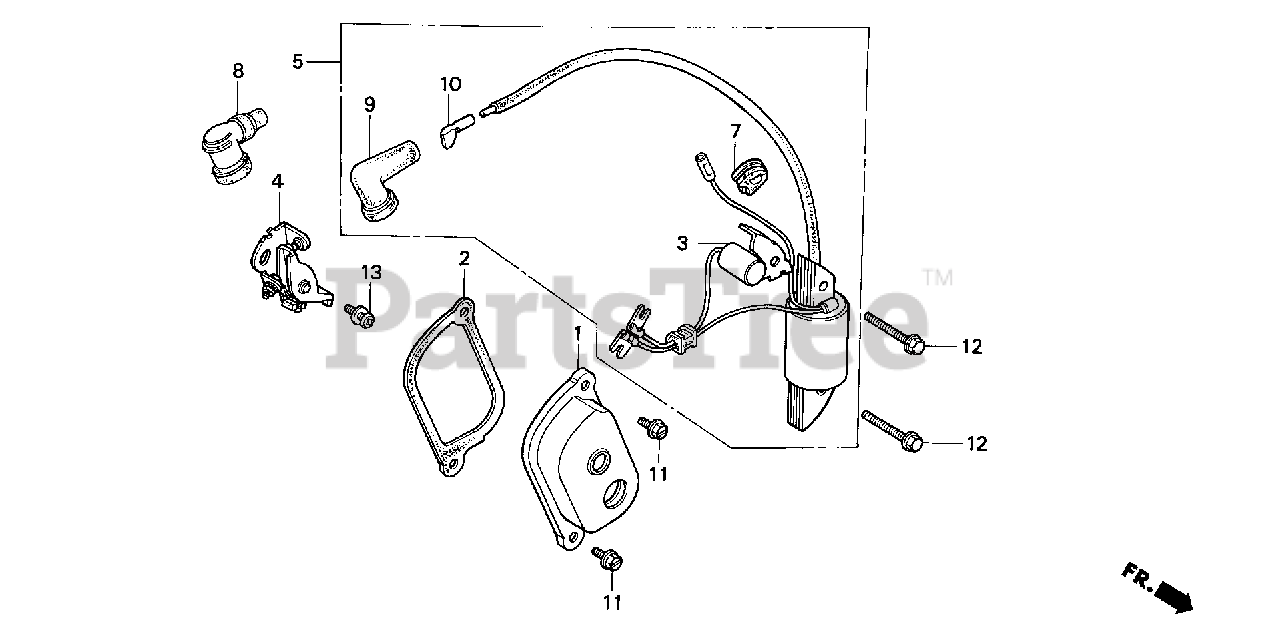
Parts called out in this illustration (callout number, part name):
1	COVER, POINTS
2	GASKET, BREAKER COVER
4	POINTS ASSY.
5	COIL ASSY., IGNITION
7	GROMMET, WIRE
9	CAP, IGNITION (TOYO)
10	TERMINAL, PLUG
11	BOLT, FLANGE (5X10)
12	BOLT, FLANGE (5X25)
13	SCREW-WASHER (5X12)
